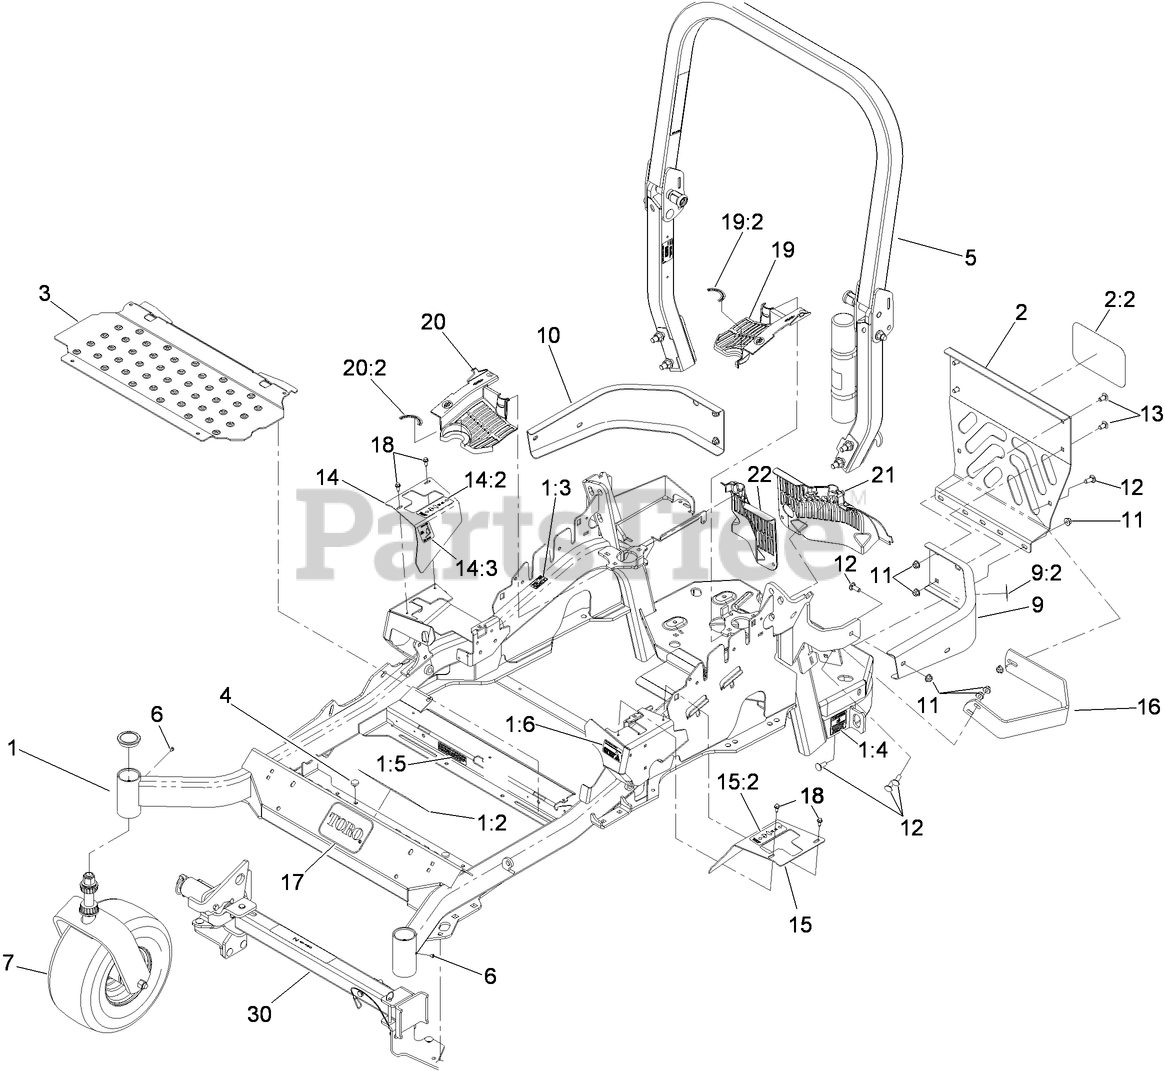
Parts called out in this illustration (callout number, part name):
1	MAIN FRAME ASM
1:2	DECAL-SLOPE
1:3	DECAL-CAUTION
1:4	DECAL-BELT DRIVE
1:5	DECAL-ARRESTER, SPARK
1:6	DECAL-FUEL FILL
2	REAR GUARD ASM
2:2	DECAL
3	FLOORPAN
4	BUMPER
5	ROPS ASM
7	FRONT CASTER ASM
9	BUMPER-REAR, LH
9:2	DECAL-CAUTION
10	BUMPER-RH
11	NUT-HF, NI
12	SCREW-CARR
13	SCREW-CARR
14	RH MOTION CONTROL COVER ASM
14:2	DECAL-MOTION CONTROL
14:3	DECAL-PARK BRAKE
15	LH MOTION CONTROL COVER ASM
15:2	DECAL-MOTION CONTROL
16	GUARD-MUFFLER
17	DECAL
18	SCREW-HWH
19	LH HYDRO GUARD ASM
19:2	DECAL-HYDRO OIL
20	RH HYDRO GUARD ASM
20:2	DECAL-HYDRO OIL
21	GUARD-HYDRO, REAR (LH)
22	GUARD-HYDRO, REAR (RH)
30	Z STAND ASM
